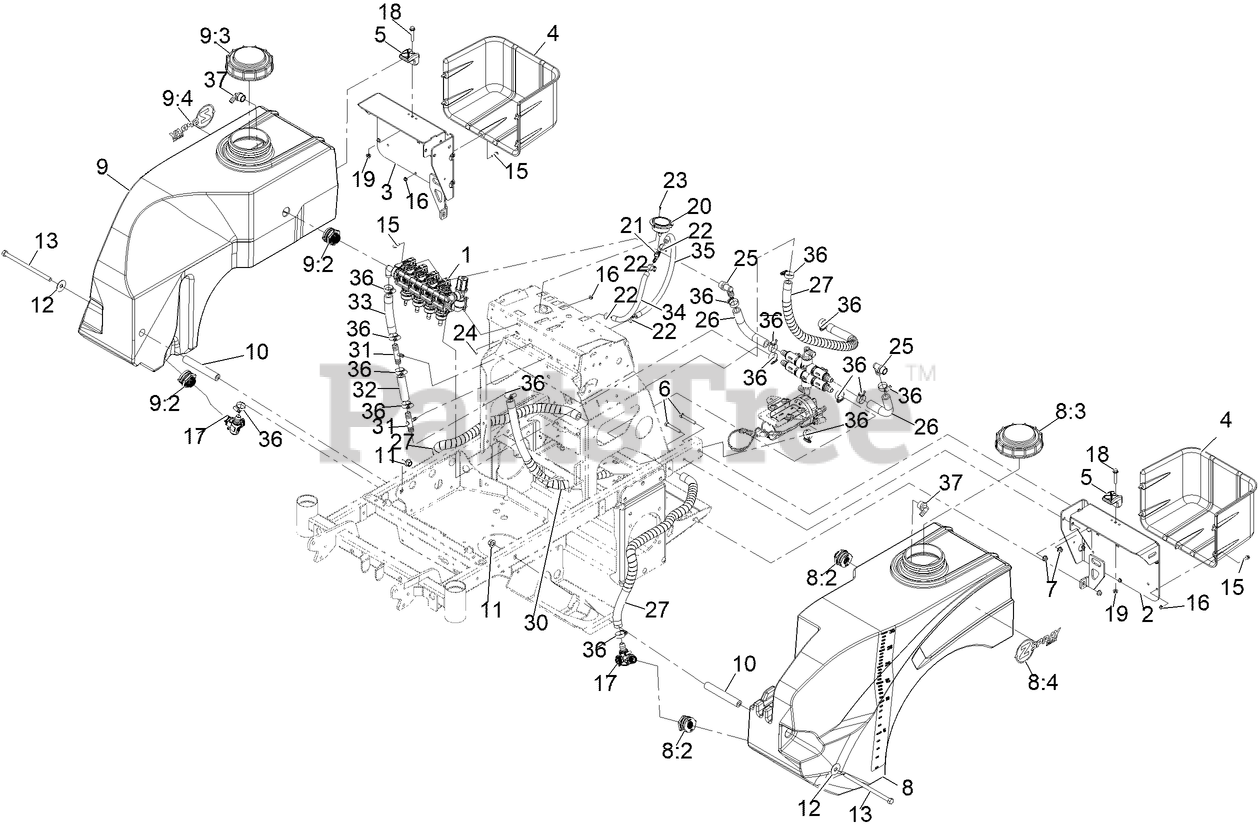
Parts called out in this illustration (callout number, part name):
1	ASM-MANIFOLD, SPRAY
2	MOUNT-TANK, LT MAX
3	MOUNT-TANK, RT MAX
4	BOX-FERTILZER, MAX
6	HHCS,3/8-16X2-1/2,ST/ST 18-8
7	Nut-Hex Flange
8	TANK-30GAL, LT
8:2	FITTING-BULKHEAD
8:3	CAP-TANK, SPRAY
8:4	DECAL-Z-SPRAY MAX LOGO
9	TANK-30GAL, RT
9:2	FITTING-BULKHEAD
9:3	CAP-TANK, SPRAY
9:4	DECAL-Z-SPRAY MAX LOGO
10	SPACER-TANK
11	NUT-HEX FLANGE
12	WASHER-FLAT, 1/2, SS
13	SCREW-HHCS
15	Screw-HHF
16	Nut-Hex Flange
17	VALVE-3 WAY
18	SCREW-HHF
19	Nut-Hex Flange
20	GAUGE-PRESSURE
21	FITTING-TEE
22	CLAMP-HOSE
23	SCR,MCH,6-32X3/8,PHPH,SST,ROHS
24	NUT-HEX
25	FITTING-ELBOW, 90
26	HOSE-SPRAY, FORMED
27	HOSE-SPRAY, WRAPPED
30	HOSE-SPRAY, WRAPPED
31	TEE-HOSE BARB
32	HOSE-SPRAY
33	HOSE-SPRAY
34	HOSE-SPRAY
35	HOSE-SPRAY
36	CLAMP-HOSE
37	FITTING-ELBOW, 90
